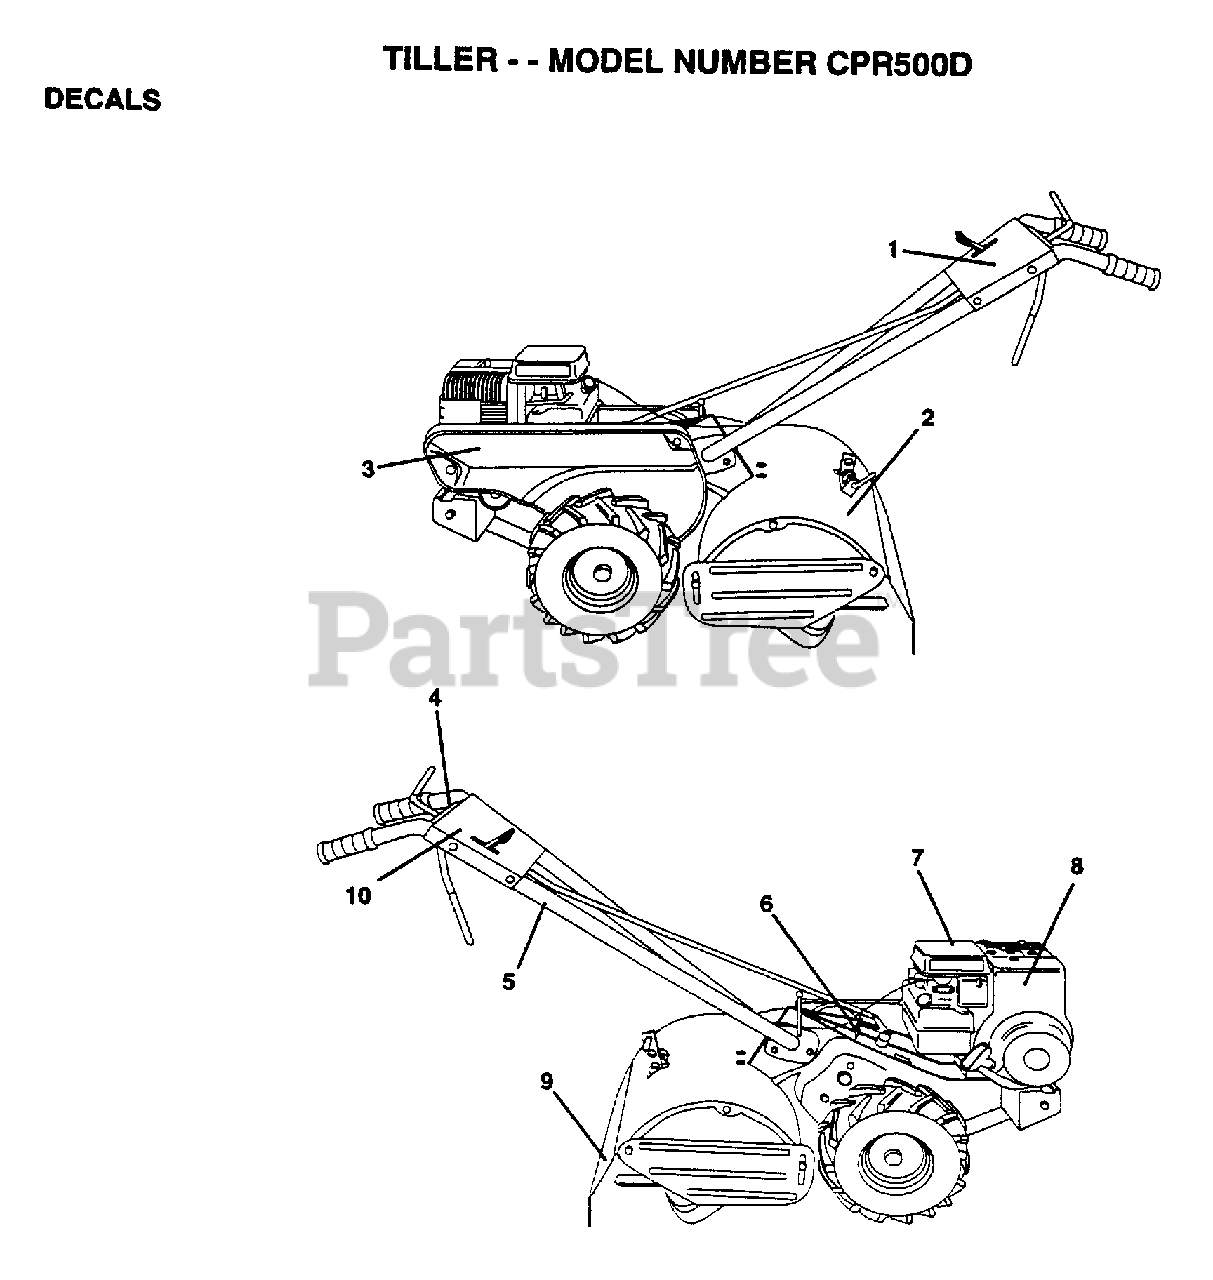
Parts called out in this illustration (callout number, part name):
1	DECAL, LOGO
2	DECAL, LOGO
3	DECAL, LOGO
5	DECAL TI
6	DECAL CRT
8	DECAL, BRIGGS & STRATTON
9	DECAL TI
10	DECAL, PANEL CONTROL
